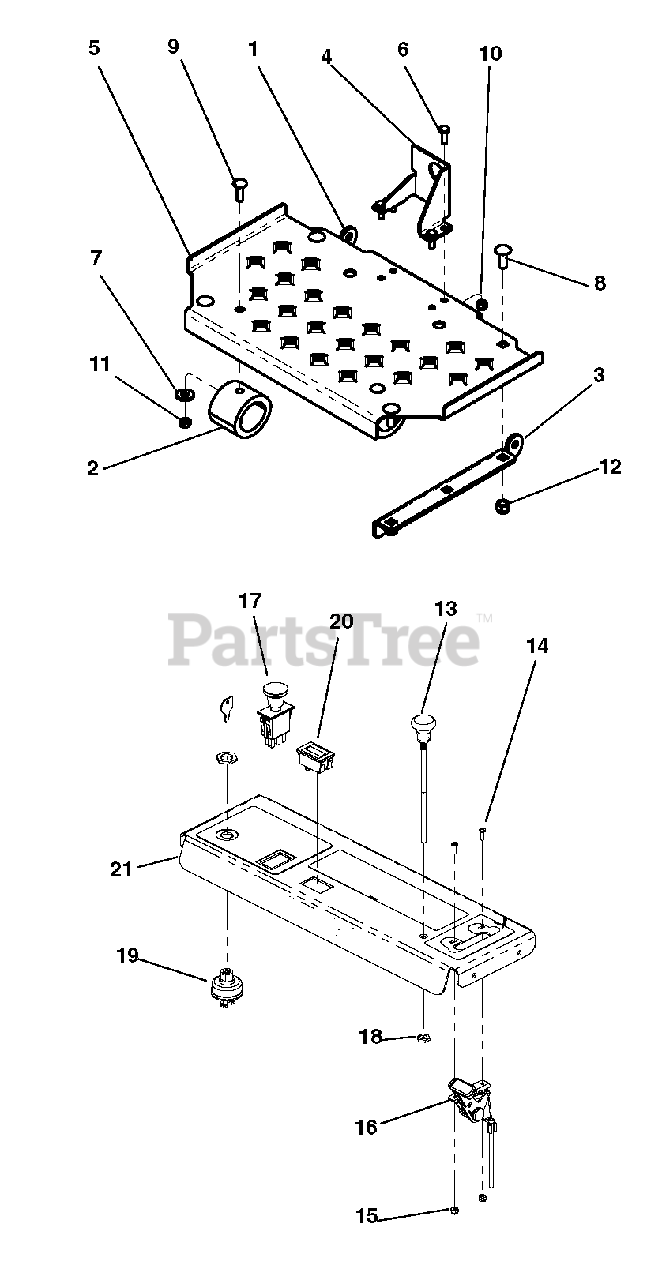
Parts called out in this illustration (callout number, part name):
1	Plate, Platform Tab LH
2	Bumper, Miner GBR-6
3	Plate, Platform Tab Left Hand
4	Anchor, Operator Presence Control
5	Platform
6	Bolt, Hex .25-20 x .75 Grade 5
7	Washer, Flat-Steel .38 x .875 x .083
8	Bolt, .375-16 x 1.00 Round Head Square Neck G 5
9	Bolt, .312-18 x 1.00 Round Head Square Neck Grade 5
10	Nut, Locking-Nylon .25-20
11	Nut, Locking-Nylon .312-18
12	Nut, Locking-Nylon .38-16
13	Cable, Choke
14	Screw, 8-32 x .50 Pan PHL Y
15	Nut, 8-32 Elastic Stop
16	Cable, Throttle
17	Switch, PTO Engagement
18	Nut, Hex .38-16
19	Switch, Key - 3 Position
20	Meter, Hour Digital
21	Top, Console w/Decals
